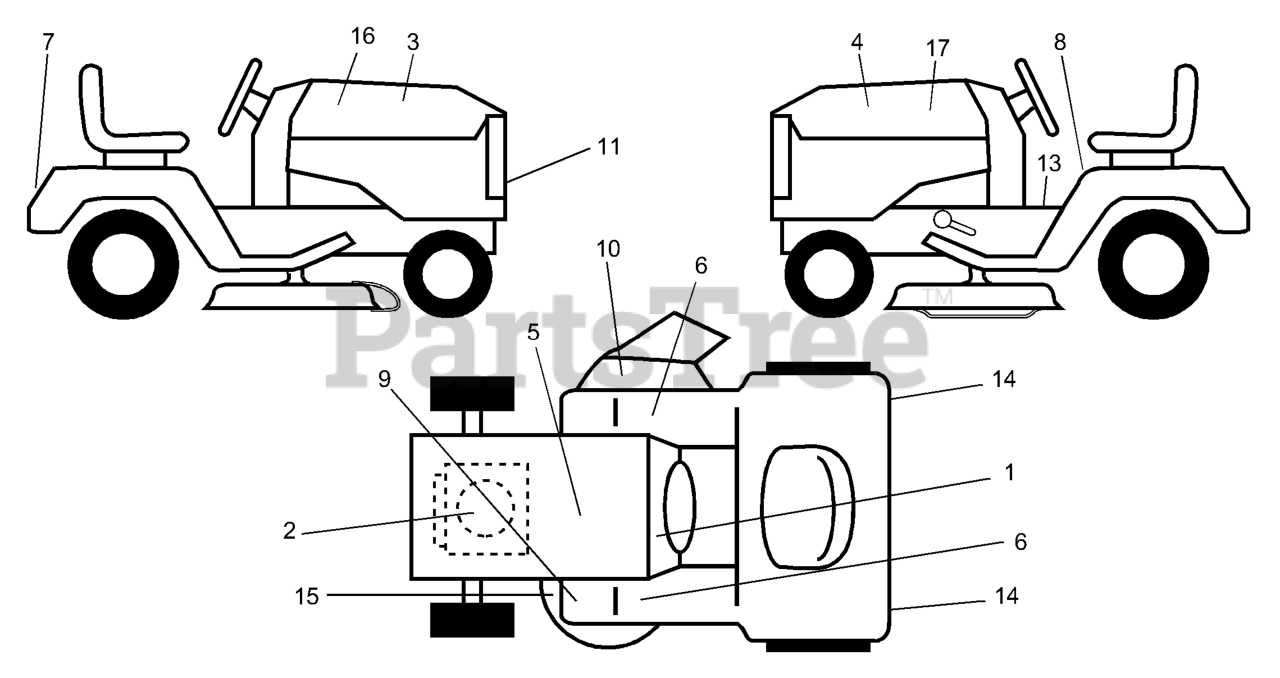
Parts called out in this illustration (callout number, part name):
2	DECAL ENGINE HP
3	DECAL-HOOD R.H.
4	DECAL-HOOD L.H.
6	PAD FOOTREST T
7	DECAL FENDER NLA
8	DECAL CAUTION
10	DECAL WARNING (ENGLISH/FRENCH)
11	DECAL GRILL HUSQ NLA
13	DECAL PARK BRAKE
14	REFLECTOR-TAIL YT
15	DECAL V-BELT SCHEMATIC
16	HOOD DECAL
17	HOOD DECAL
